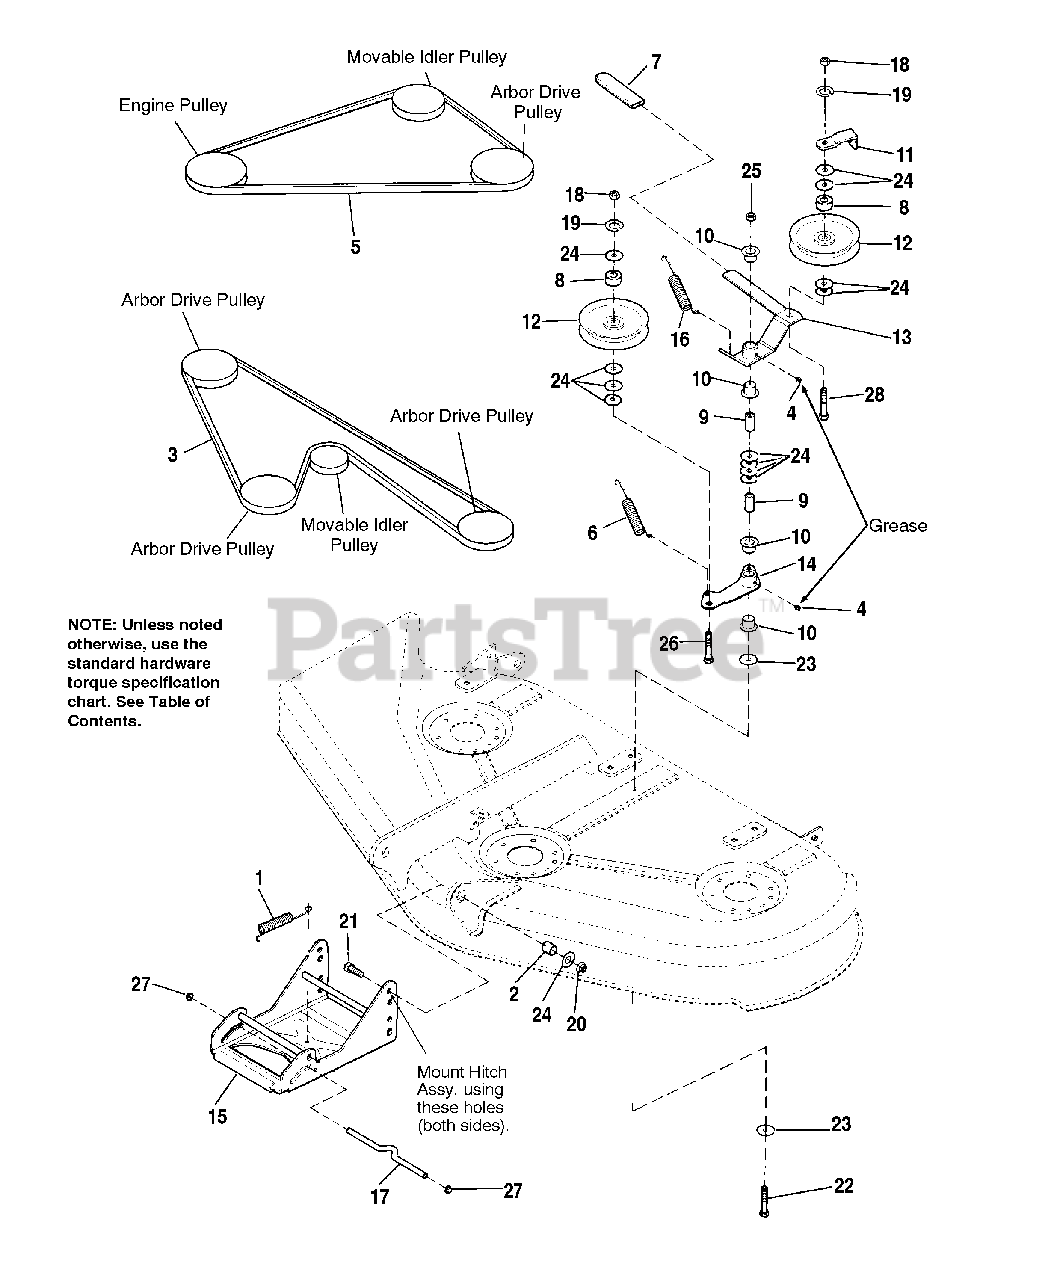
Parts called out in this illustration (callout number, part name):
1	SPRING
3	V-BELT, Arbor Drive
4	GREASE FITTING
5	V-BELT, Mower Drive
7	GRIP, Lever
11	IDLER, Stop
12	PULLEY, Idler
13	LEVER ASSY, Idler
14	LEVER ASSY., Idler Arm
15	HITCH ASSY.
18	NUT, Hex, 3/8-16
19	LOCKWASHER, 3/8
20	NUT, Hex, Lock, 3/8-16
21	CAPSCREW, Hex Hd., 3/8-16 x 1-1/2
22	CAPSCREW, Hex Hd., 3/8-16 x 3-1/2
23	WASHER
24	WASHER, 5/16
25	NUT, Hex, Flange, Two-Way Lock, 3/8-16
26	CARRIAGE BOLT, 3/8-16 x 1-1/2
27	NUT, Push On
28	CARRIAGE BOLT, 3/8-16 x 2
